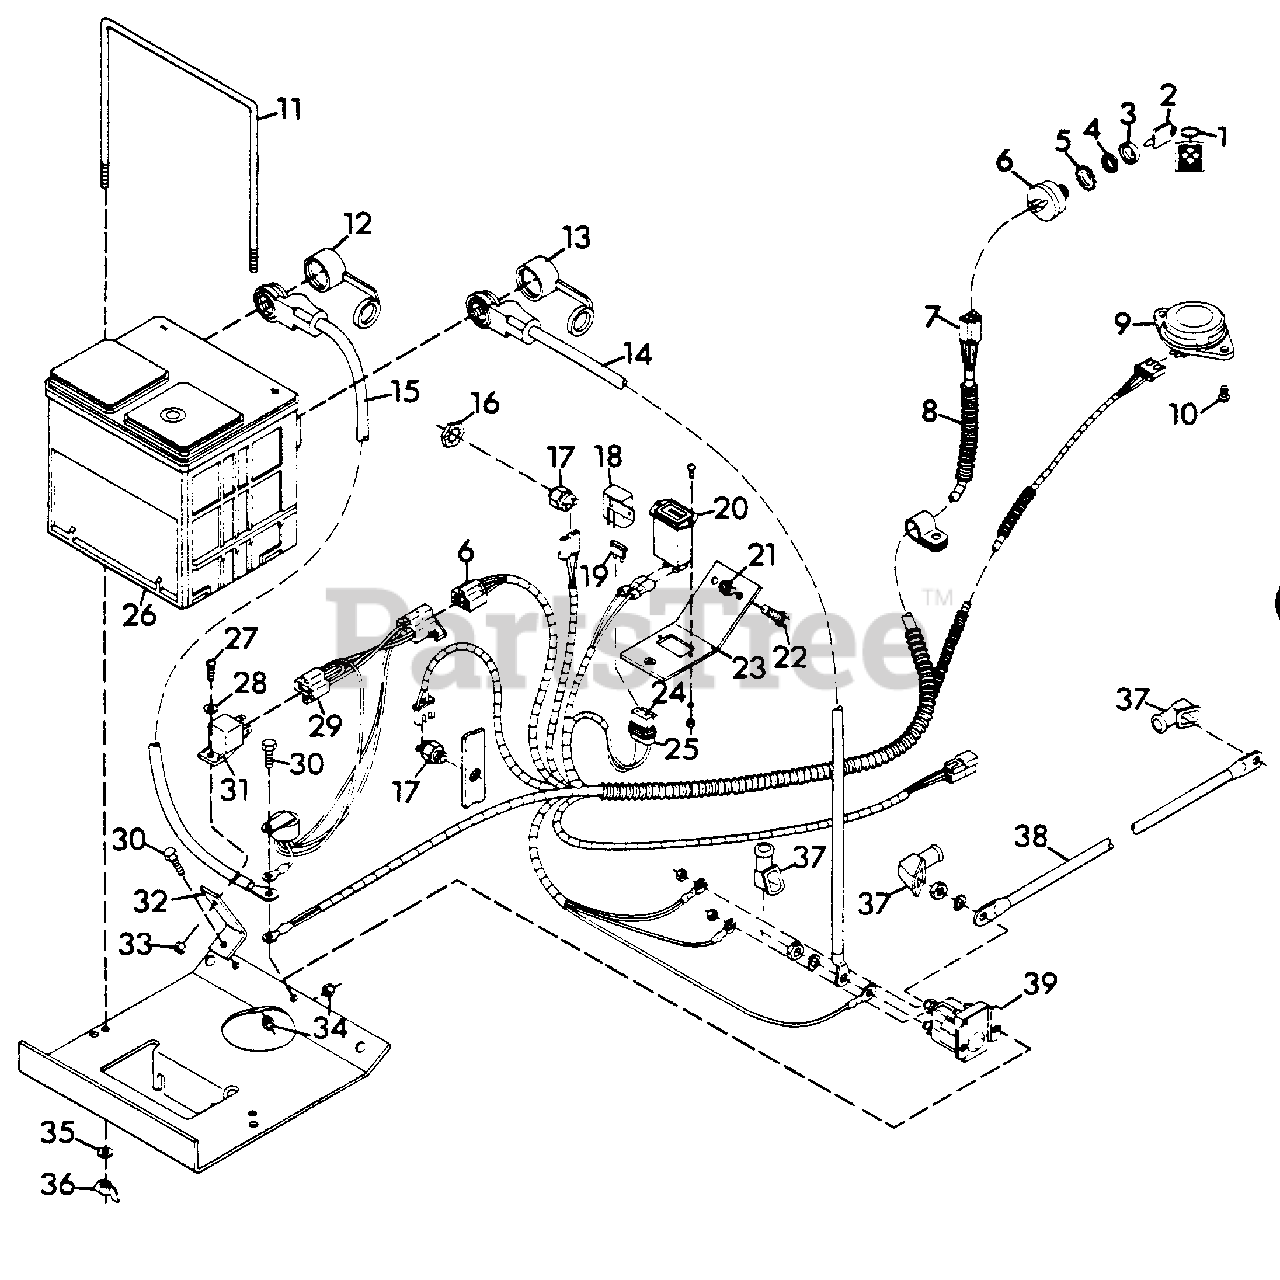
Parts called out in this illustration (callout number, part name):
1	CHAIN, KEY
2	KEY, IGNITION SWITCH
3	BOOT, FOR 9/16 SWITCH
4	NUT, 9/16-24 FOR SWITCH
5	WASHER, LOCK
6	SWITCH, IGNITION
7	CONNECTOR
8	HARNESS, WIRING PRO MASTER-50
9	SWITCH, SEAT
10	SCREW, MACHINE 1/4-20X.50
11	ROD, BATTERY
12	COVER, BATTERY NEG.
13	COVER, BATTERY POS.
14	CABLE, ELECTRICAL
15	CABLE, ELECTRICAL
16	NUT, STAMPED 9/16-18
17	SWITCH, INTERLOCK
18	COVER
19	FUSE, 25 AMP
20	HOURMETER
21	NUT, LOCK 3/8-16
22	BOLT, HEX 3/8-16X.875
23	BRACKET
24	TERMINAL, 14-16 GAUGE
25	CONNECTOR
26	BATTERY, DELCO MAINTENANCE-FREE #101 -REPLACEMENT BATTERY #83-50
27	SCREW, MACH. 10-24X.75 PHD
28	WASHER, FLAT .188X.438X.049
29	MODULE, TIME DELAY
30	BOLT, HEX 1/4-20X1.00
31	RELAY
32	BRACKET, FUEL LINE SUPPORT
33	NUT, LOCK 10-24
34	NUT, LOCK 1/4-20
35	WASHER, FLAT .281X.625X.065
36	NUT, WING 1/4-20
37	BOOT, BATTERY CABLE
38	CABLE
39	SWITCH, MAGNETIC
